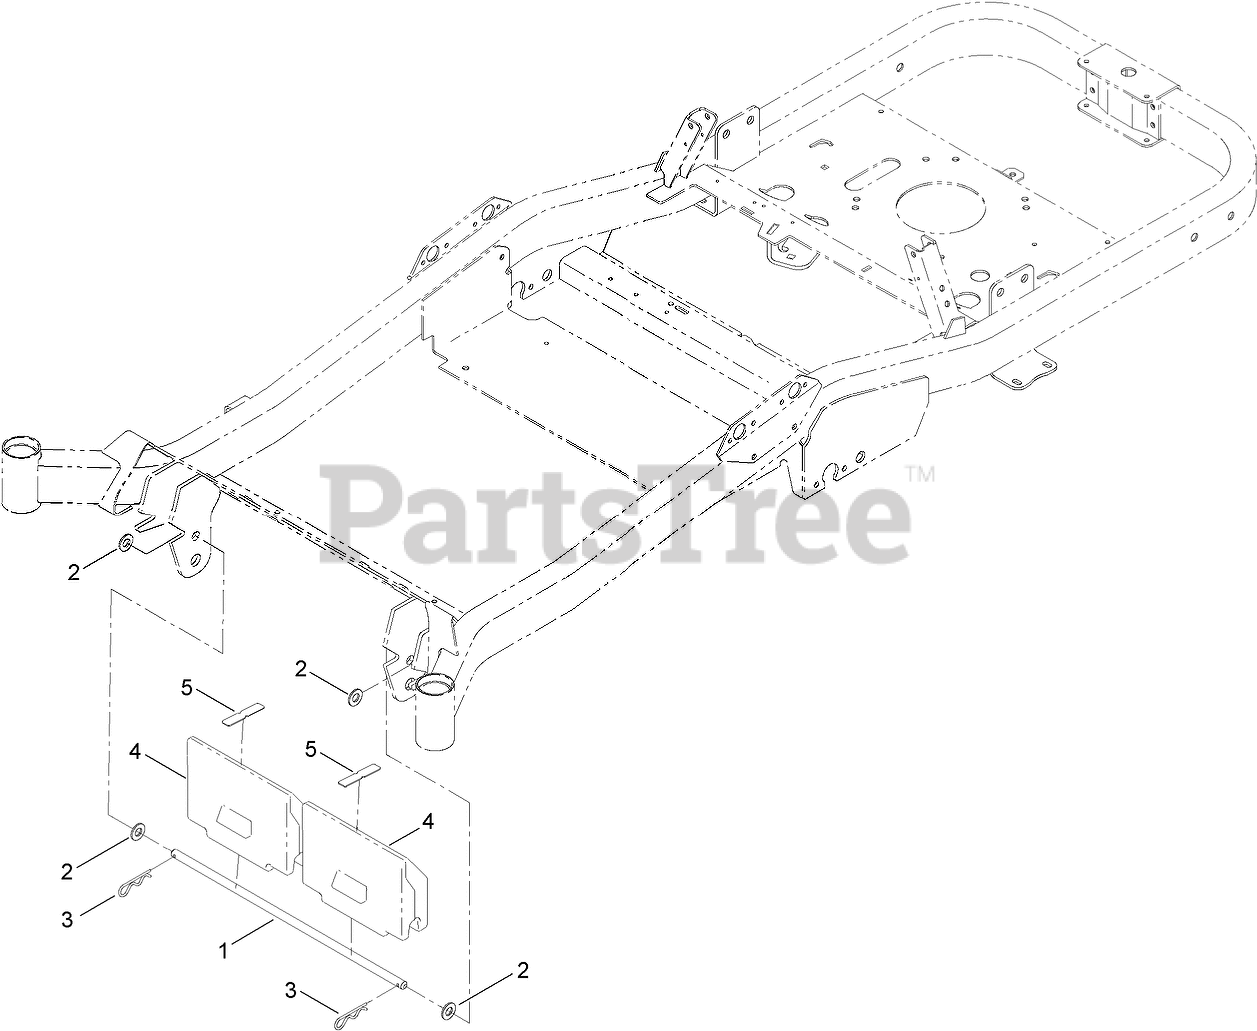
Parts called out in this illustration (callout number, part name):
1	ROD-DECK, PIVOT
2	WASHER-FLAT
3	PIN-HAIR
4	WEIGHT-BAGGER
5	BUMPER-PAD
